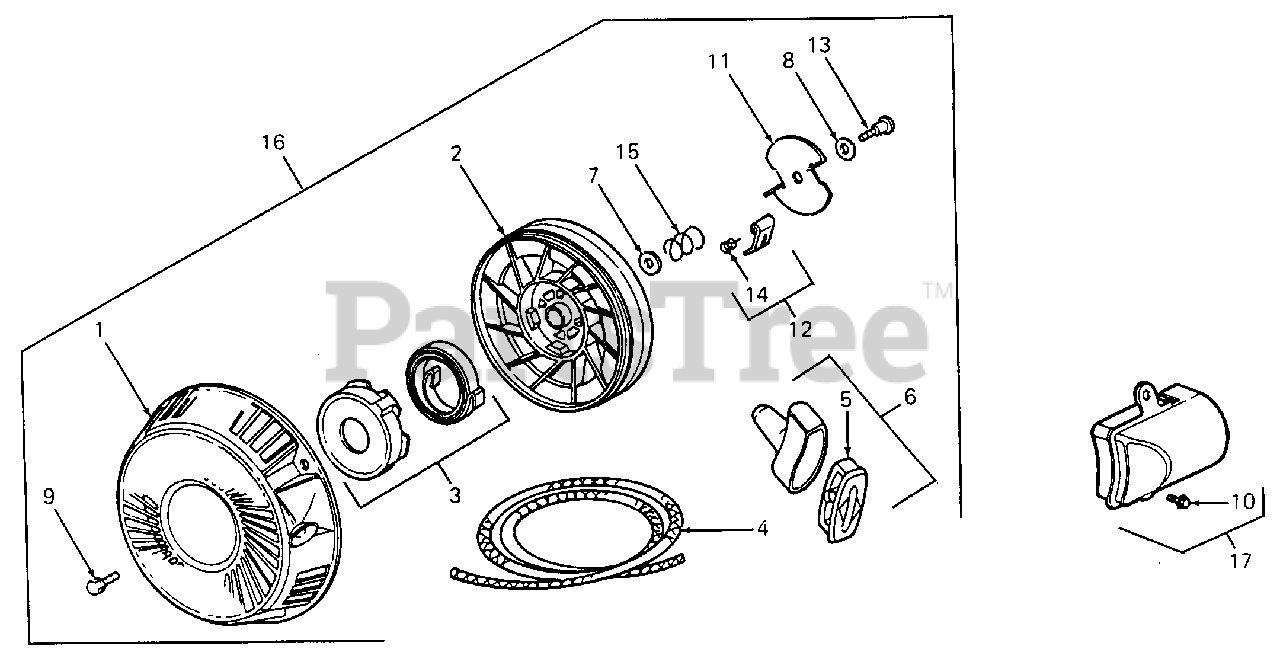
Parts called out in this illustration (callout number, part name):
1	Housing, Starter
2	Pulley, Rewind Starter
3	Spring, Rewind Starter
4	Rope, Starter
5	Insert, Starter Handle
6	Grip, Starter
7	Washer, Pulley
8	Washer, Retainer
9	Screw, Sems
13	Screw, Retainer
14	Spring, Dog
15	Spring, Torsion
16	Starter Assy
17	Shield, Starter
